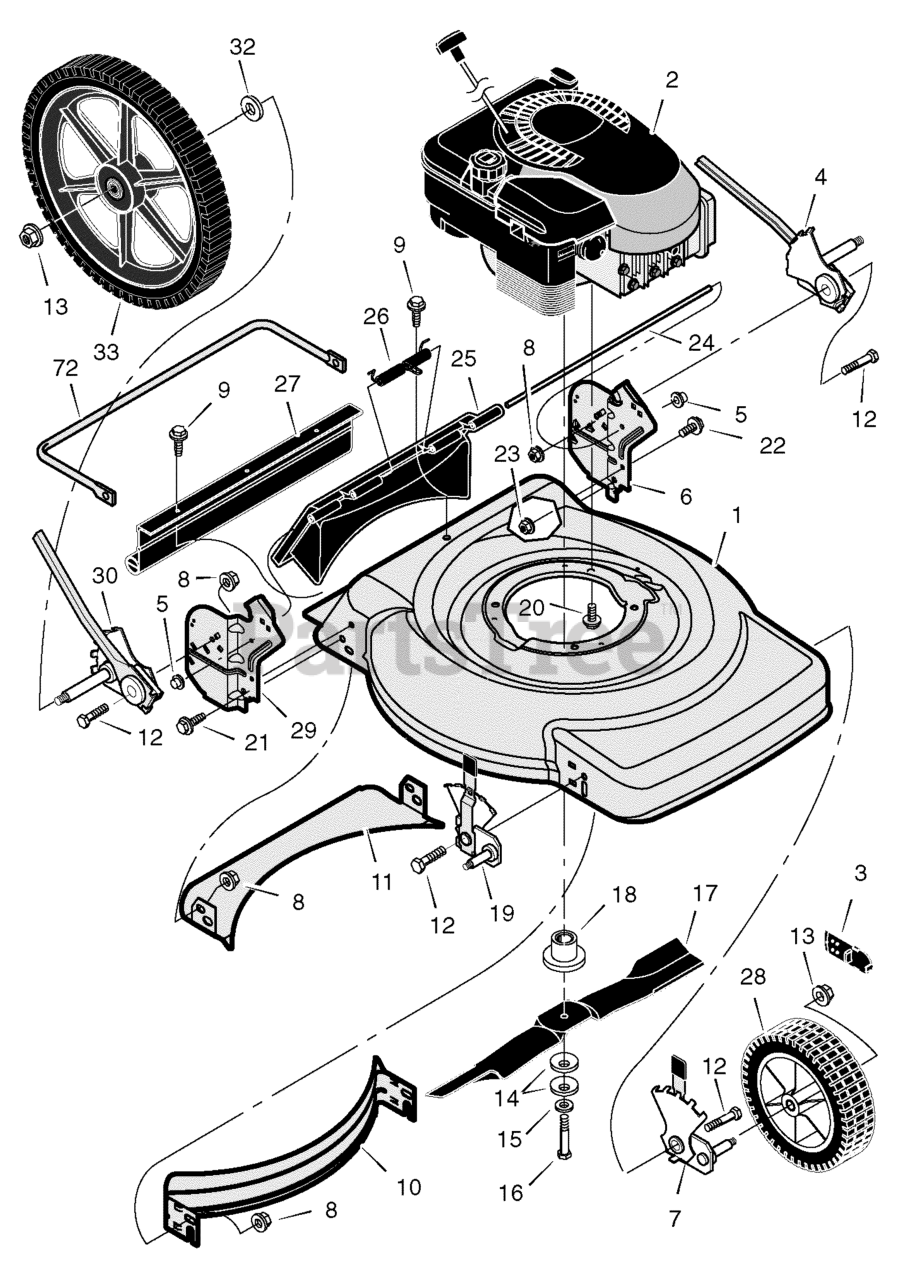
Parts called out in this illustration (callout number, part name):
1	Housing
2	Engine *
3	Cap, Hub (Optional)
4	Adjuster, Left Rear Height
5	Push On Cap
6	Bracket, Left Handle
7	Adjuster, Left Front Height
8	Nut, Flange
10	Baffle, Front
11	Baffle, Rear
13	Nut, Flange
14	Washer, Belleville
15	Washer
18	Adapter, Blade
19	Adjuster, Right Front Height
20	Bolt, Engine
21	Bolt
22	Bolt
23	Nut, Flange
24	Rod, Pivot
25	Door, Rear (Black)
25	Door, Rear (Gray)
26	Spring
27	Guard, Rear
28	Wheel & Tire *
29	Bracket, Right Handle
30	Adjuster, Right Rear Height
32	Washer
33	Wheel, Rear *
